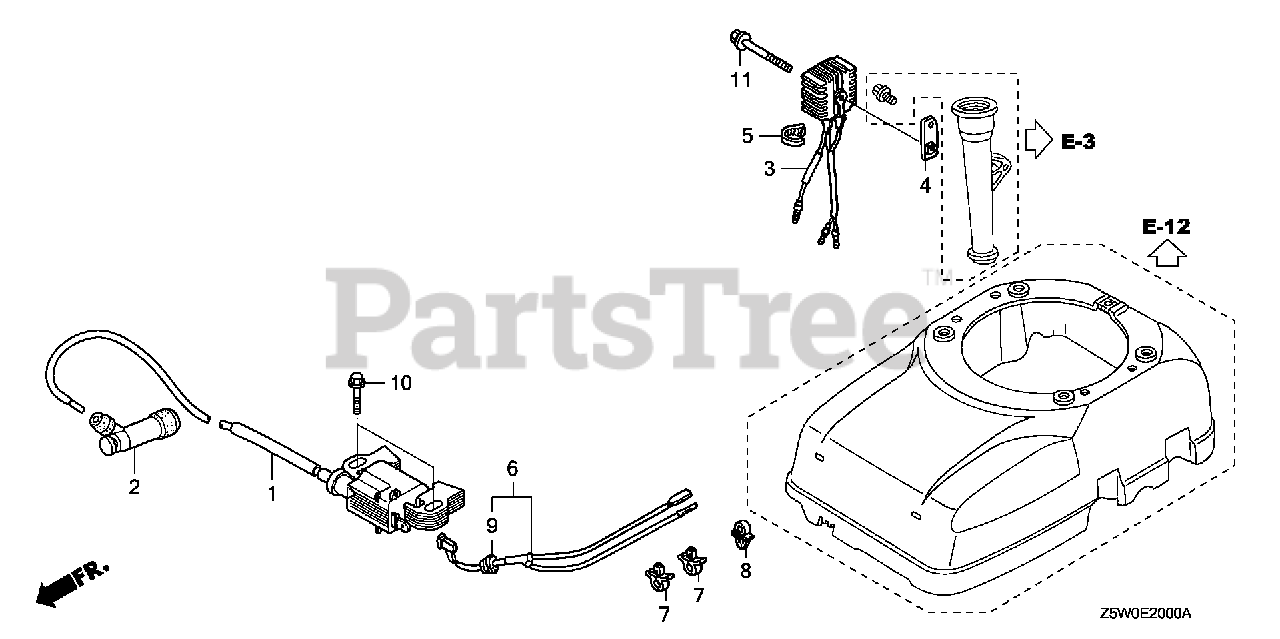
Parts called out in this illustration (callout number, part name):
1	COIL ASSY., IGNITION
2	CAP ASSY., NOISE SUPPRESSOR
6	WIRE, STOP SWITCH
7	CLIP, BRAKE PIPE (A)
8	HOLDER, WIRE (FASTEX)
9	GROMMET, WIRE CORD
10	BOLT, FLANGE (6X28) (CT200)
